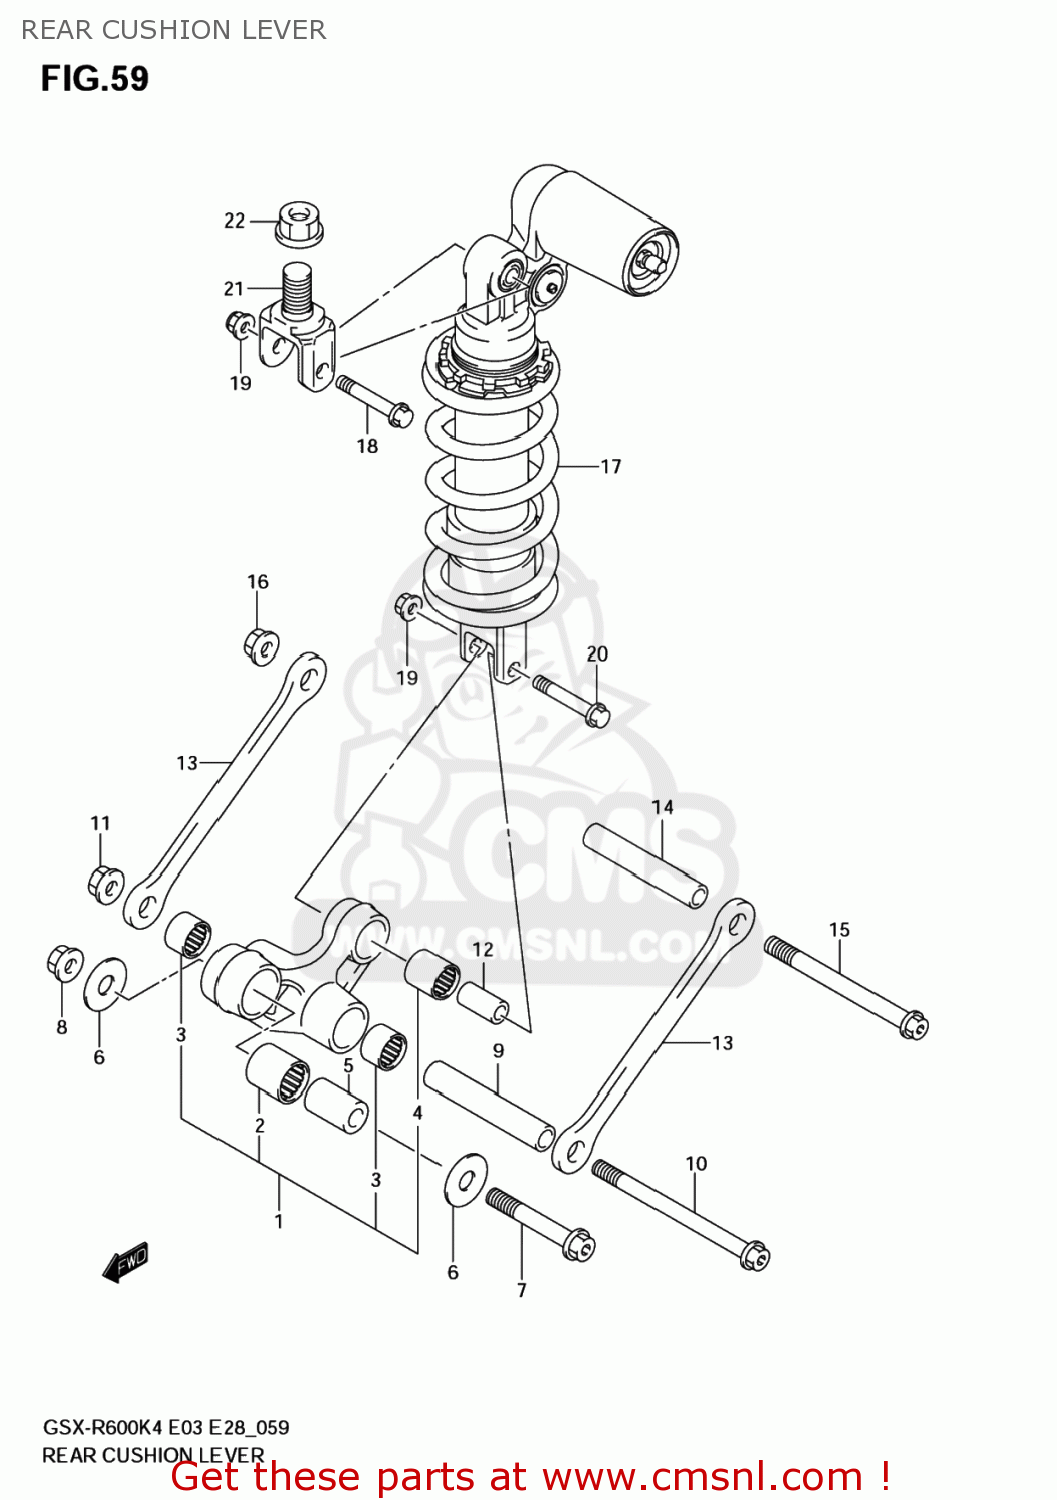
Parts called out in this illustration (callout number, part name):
1	LEVER SET, REAR CUSHION
2	BEARING(20X27X30)
3	BEARING(17X24X20)
4	BEARING(17X24X26)
5	SPACER,RR CUSHION LEVER FR
6	WASHER(12X34X1)
7	BOLT,RR CUSHION LEVER FR
8	NUT
9	SPACER,RR CUSHION LEVER CTR
10	BOLT,RR CUSHION LEVER CTR
11	NUT
12	SPACER,RR CUSHION LEVER
13	ROD,RR CUSHION
14	SPACER,RR CUSHION LEVER CTR
15	BOLT,RR CUSHION LEVER CTR
16	NUT
17	ABSORBER ASSY,RR SHOCK
18	BOLT(10X55)
19	NUT
20	BOLT(10X55)
21	BRACKET,RR SHOCK ABSORBER UPR
22	NUT
